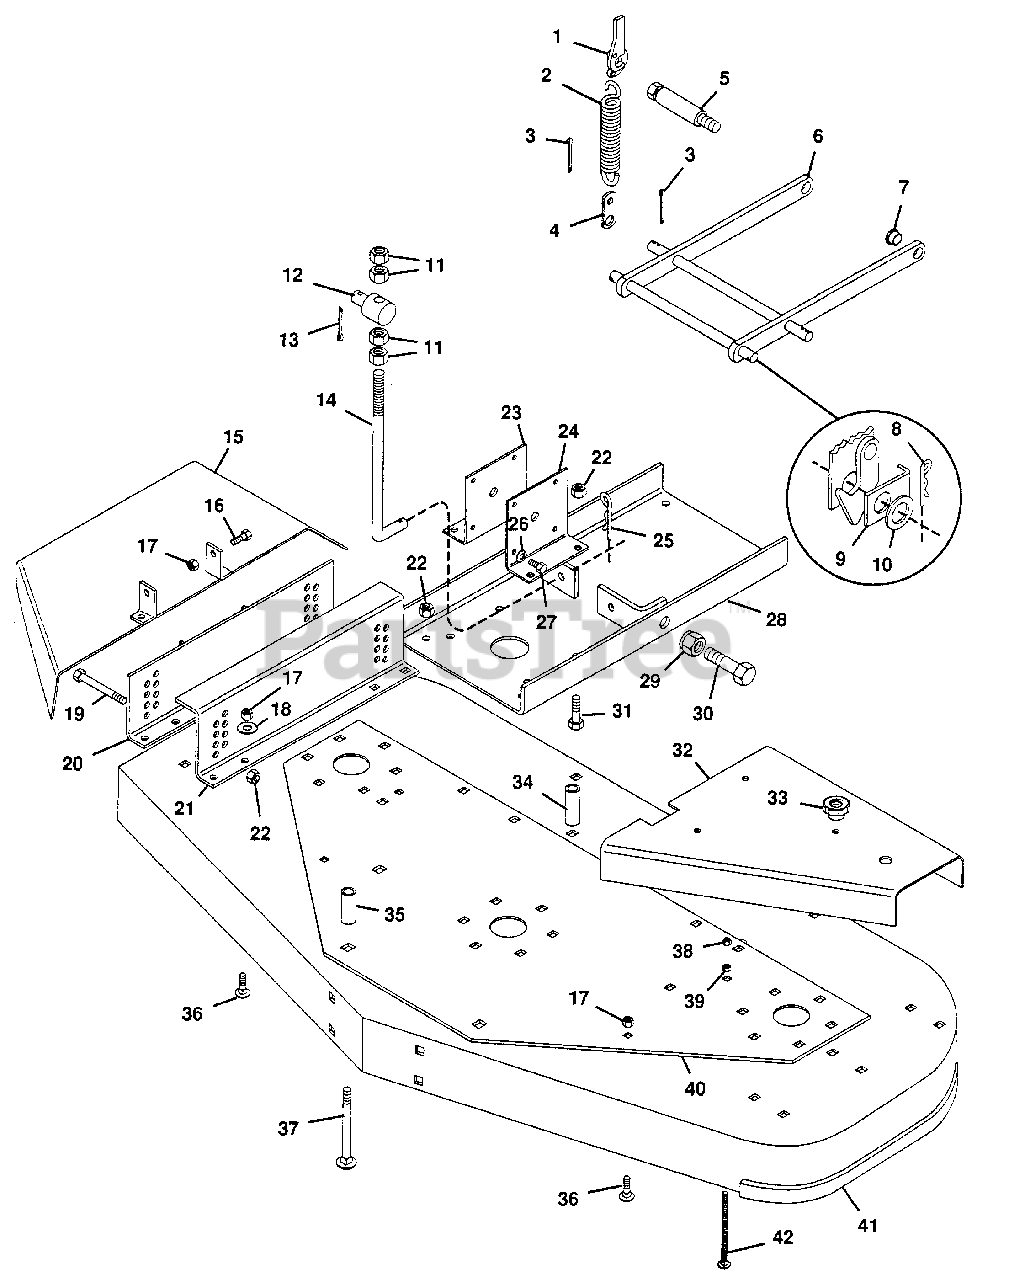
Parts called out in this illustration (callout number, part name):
1	Latch, Spring Assembly R.H.
2	Spring, Ext. 7.625x1.50x.70 Rate
3	Pin, Cotter .125x1.25
4	Latch, Spring Assembly L.H.
4	Strap
5	Latch, Pin
6	Weldment, Mower Mounting
7	Bush., Flg. 764x1.47x.560 Ny.
8	Pin, Hair
9	Keeper, Mower Pivot
10	Washer, Flat .813x1.37x.100
11	Nut, Jam 1/2-13 Hex
12	Pivot, Mower Lift
13	Pin, Cotter .187x1.25
14	Rod, Lift
15	Weldment, Discharge Chute
16	Bolt, Hex 3/8-16x1.00
17	Nut, Lock 3/8-16
18	Washer, Flat .406x.812x.065
19	Bolt, Hex 1/2-13x3.50
20	Weldment, 60" Hanger
21	Hanger, Inner
22	Nut, Lock 1/2-13
23	Bracket, Gearbox R.H.
24	Bracket, Gearbox L.H.
25	Pin, Cotter Hair
26	Washer, Lock 3/8 Reg.
27	Bolt, Hex 3/8-16x.875
28	Weldment, Support Plate
29	Nut, Lock 3/4-10
30	Bolt, Hex 3/4-10x2.75
31	Bolt, Hex 1/2-13x1.25
32	Cover, Belt L.H.
32	Cover, Belt R.H.
33	Knob
34	Bush., St. .562x1.00x2.18 Stl.
35	Bush., St. .562x1.00x2.00 Stl.
36	Bolt, 3/8-16x1.00 Rd Hd Sq Nk
37	Bolt, 1/2-13x3.50 Rd Hd Sq Nk
38	Nut, Lock 5/16-18
39	Nut, Jam 5/16-18 Hex
40	Plate, Deck Support
41	Weldment, 60" Mower Deck
42	Bolt, 5/16-18x4.0 Rd Hd Sq Nk
